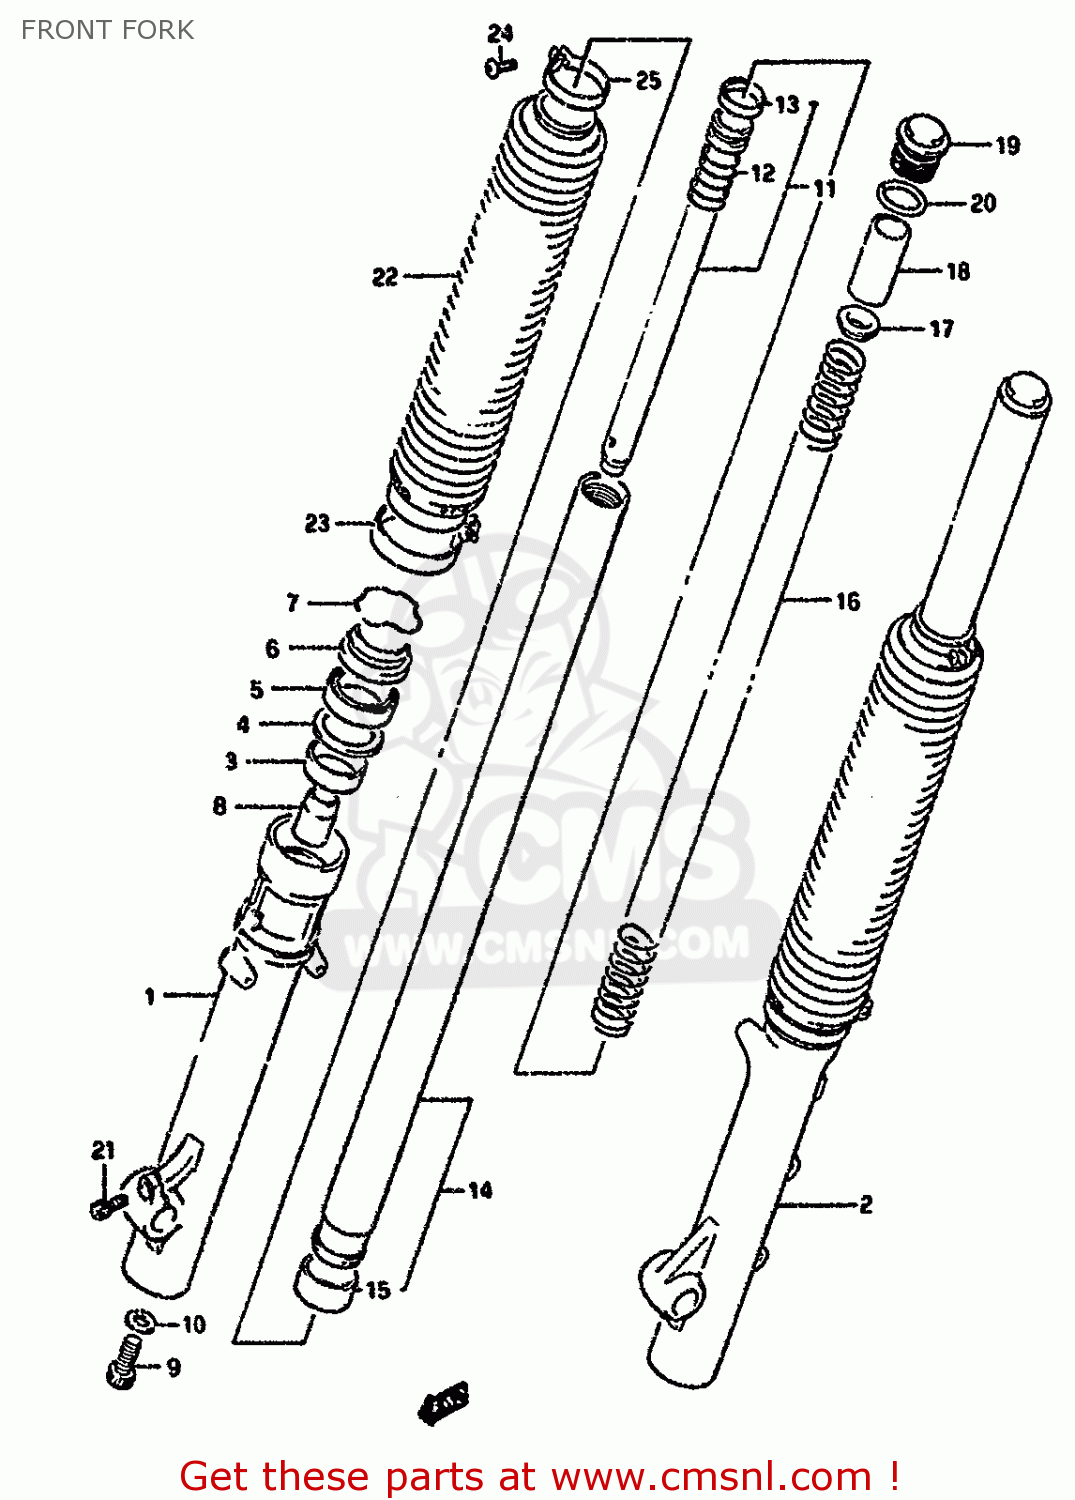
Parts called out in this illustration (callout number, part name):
1	TUBE,OUTER,R
2	TUBE, OUTER LH
3	METAL,SLIDE
4	WASHER
5	SEAL,OIL
6	SEAL,DUST
7	RING,STOPPER
8	PIECE,OIL LOCK
9	BOLT(14X25)
10	GASKET (NAS)
11	CYLINDER
12	SPRING,REBOUND
13	RING,PISTON
14	TUBE,INNER
15	PISTON
16	SPRING
17	GUIDE,SPRING
18	SPACER,FRONT FORK SPRING
19	CAP,FORK
20	O RING
21	BOLT,SOCKET HEAD(8X22)
22	BOOT
23	BAND,BOOT LWR
24	SCREW,BAND BOOT(3.5X10)
25	BAND,BOOT UPR
